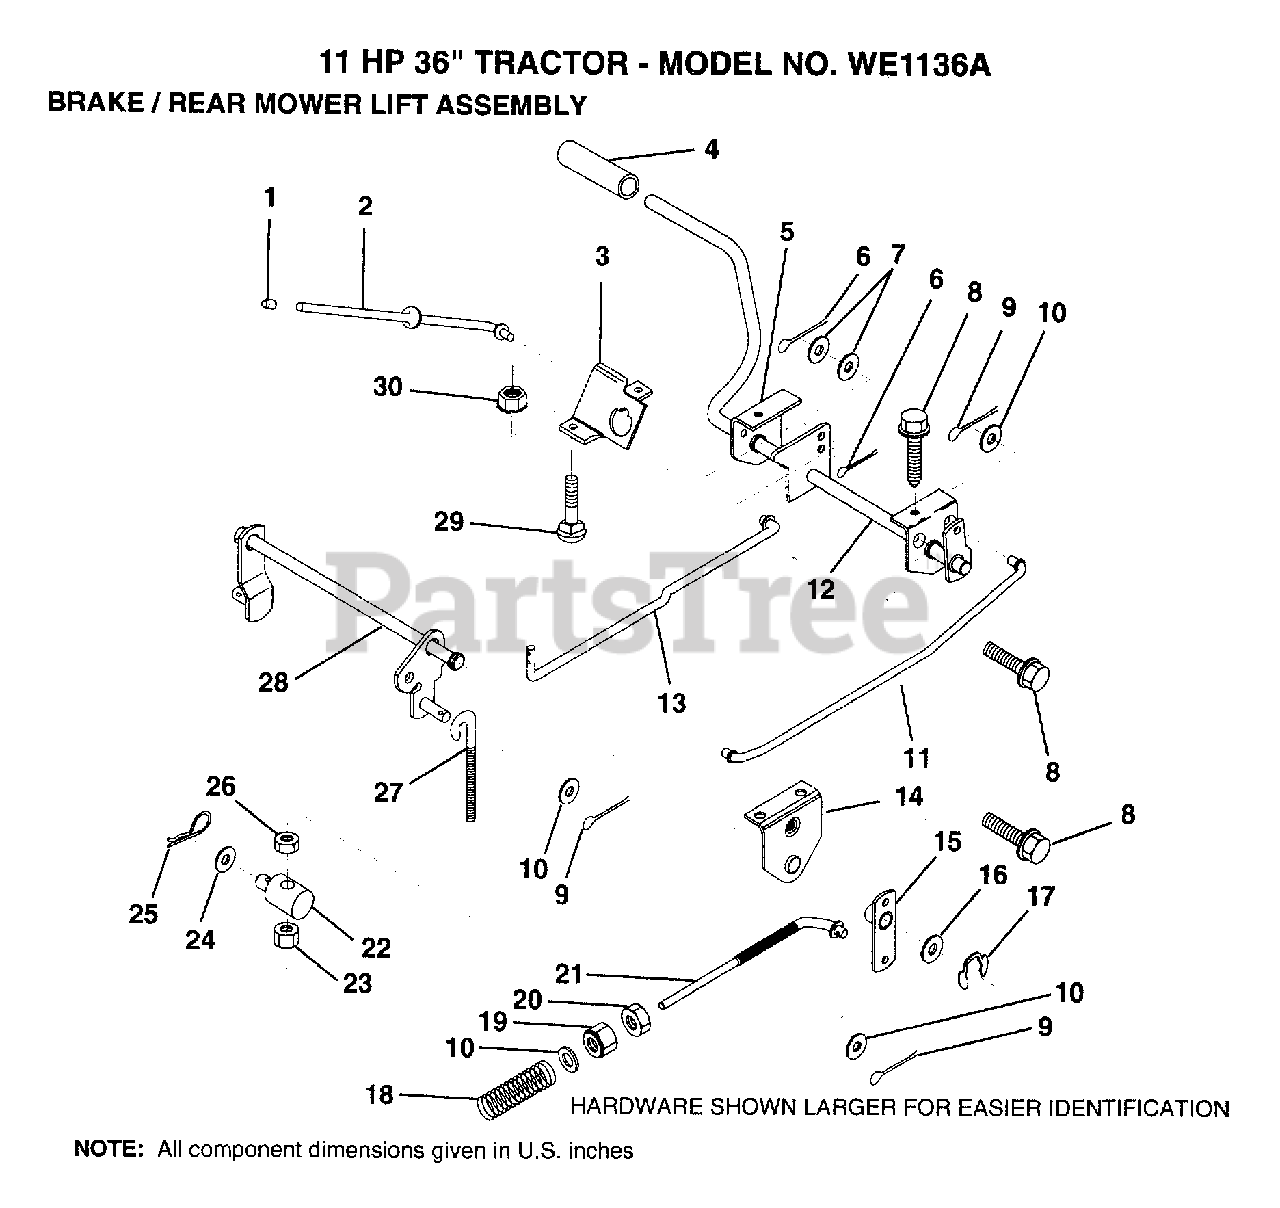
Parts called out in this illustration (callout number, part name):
1	PLUNGER CAP T
2	"ROD,PARK BRAKE"
3	"BRKT,PARK BRAKE"
4	FOOT PEDAL COVER
5	"BRKT,CLU PEDAL LH"
7	WASHER
8	SCREW LT
9	COTTER PIN
10	WASHER
11	"ROD,FRT BRAKE"
13	"ROD,CLUTCH"
14	"BRKT,LIFT SHAFT"
15	BRAKE PIVOT ARM
16	WASHER T
17	KLIP RING
18	SPRING ROD LT
20	NUT
24	WASHER
25	SPRING.RETAINER
26	LOCKNUT
27	"LINK, MOWER REAR"
